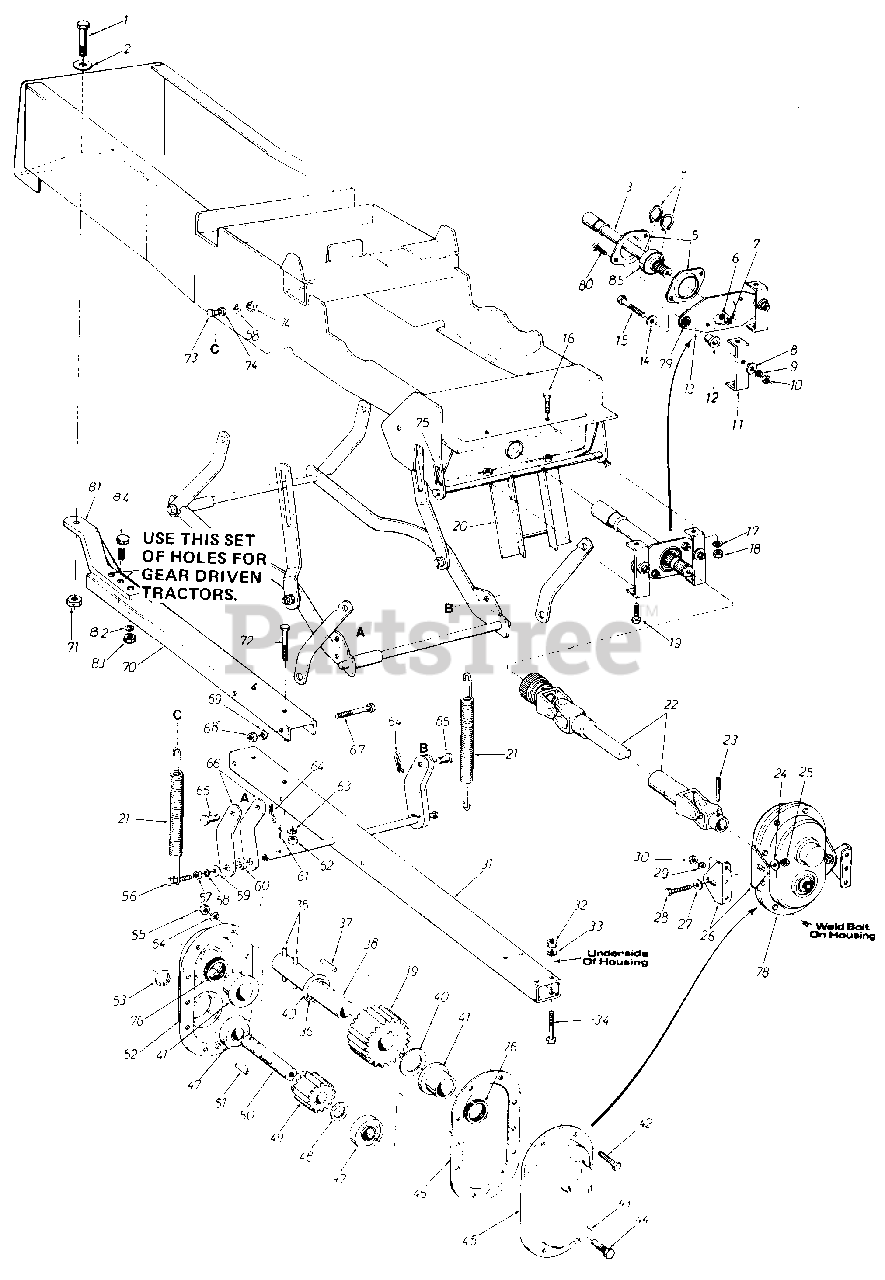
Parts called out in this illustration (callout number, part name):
1	Hex Scr. 5/8-18 x 1.31" Lg.
2	Fl.-Wash. .66" I.D. x 1.25" O.D. x .100
3	P.T.O. Shaft Extension Ass'y.
4	Retaining Ring 1.00" Dia. Shaft
5	Flangette Bearing
6	L.-Wash. 5/16" Scr.*
7	Hex Nut 5/16-18 Thd.*
8	Fl.-Wash 3/8" I.D. x 1.00" O.D.
9	L Wash. 3/8" Scr.
10	Hex Nut 3/8-24 Thd.*
11	P.T.O. Bearing Retainer Brk't.
12	Shoulder Spacer
13	P.T.O. Bearing Retainer Plate
14	Fl.-Wash. 3/8" I.D. x 1.00 O.D.
15	Hex Scr. 3/8-24 x 1.50" Lg.*
16	Hex Scr. 3/8-16 x .75" Lg.*
17	L.-Wash. 3/8" Scr.*
18	Hex Nut 3/8-16 Thd.*
19	Hex Scr. 3/8-16 x .75" Lg.*
20	Guide Bracket Ass'y.
21	Helper Spring .94 O.D. x 7.38" Lg.
22	Universal Drive Shaft Ass'y.
23	Spring Pin Spirol 5/16" x 2.50" Lg.
24	Belleville Wash. .341 I.D. x .88 O.D.
25	Hex Nut 5/16-8 Thd.*
26	Gear Box Support Bracket
27	Belleville Wash. .34 I.D. x .88 O.D.
28	Hex Scr. 5/16-18 x .75" L.g*
29	L.-Wash. 5/16" Scr.*
30	Hex Nut 5/16-18 Thd.*
31	Lift Shaft Ass'y.
32	Hex Ins.Jam L.-Nut 3/8-24 Thd.
33	L.-Wash. 3/8" Scr.*
34	Hex Scr. 3/8-24 x 2.75" Lg.*
35	Spring Pin Spirol 5/16" Dia. 1.75" Lg.
36	Snap Ring for 1.25" Dia. Shaft
37	Sq. Key 1/4" x 1.00" Lg.
38	Gear Shaft
39	28 Teeth Spur Gear
40	Fl.-Wash. 1.31" I.D x 2.00" O.D. x .060
41	Flange Bearing 1.25" I.D. x 1.75" O.D.
42	Hex Screw 1/4 28 x .88 " Lg
43	Fl. Wash. .40" I.D. x 1.25" O.D. x .160
44	Hex L.-Scr. 3/8-24 x 1.00" Lg.
45	Complete Gear Housing Half-L.H.
46	Gasket
47	Ball Bearing 1.00" I.D. x 2.00" O.D.
48	Fl.-Wash. 1.03" I.D. x 1.63" O.D. x .090
49	15 Teeth Spur Gear
50	Input Shaft
51	Woodruff Key 1/4 x 3/4" Dia.
52	Complete Gear Housing Half-R.H.
53	Snap Ring for 1.00" Dia. Shaft
54	L.-Wash. 1/4" Scr.*
55	Hex Nut 1/4-28 Thd.
56	Hex Scr. 5/16-18 x 1.75" Lg.*
57	Hex Nut 5/16-18 Thd.*
58	L.-Wash. 5/16" Scr.*
59	Fl.-Wash. .344 I.D. x 1.12 O.D. x .125
60	Spacer .81" I.D. x 1.00" O.D. x .31
61	Cotter Pin.6/32" Dia. x 1.00" Lg.*
62	Hex Ins. Jam L.-Nut 3/8-24 Thd.
63	L.-Wash. 3/8 Scr.*
64	Intern. Cotter Pin 1/2" Dia.
65	Clevis Pin .500" Dia.
66	Lift Bracket
67	Hex Scr. 3/8-24 x 4.50" Lg.*
68	Hex Ins.Jam L.-Nut 3/8-24 Thd.
69	L.-Wash. 3/8 Scr.*
70	Lift Bracket
71	Hex Ins. Jam L.-Nut 5/8-18 Thd.
72	Hex Scr. 3/8-24 x 2.75" Lg.*
73	Hex Scr. 5/16-18 x 1.75" Lg.*
74	Hex Nut 5/16-18 Thd.*
75	Intern. Cotter Pin 3/4" Dia.
76	Oil Seal 1.25" I.D. x 1.75" O.D. x .26
78	Gear Box Ass'y. Comp.
79	Rubber Grommet .50" I.D.
80	Carriage Bolt 5/16-18 x .75" Lg.*
83	Hex Nut 1/2-13 Thd.
84	Hex Scr. 1/2-13 1-1/4 Lg.
85	Ball Bearing
